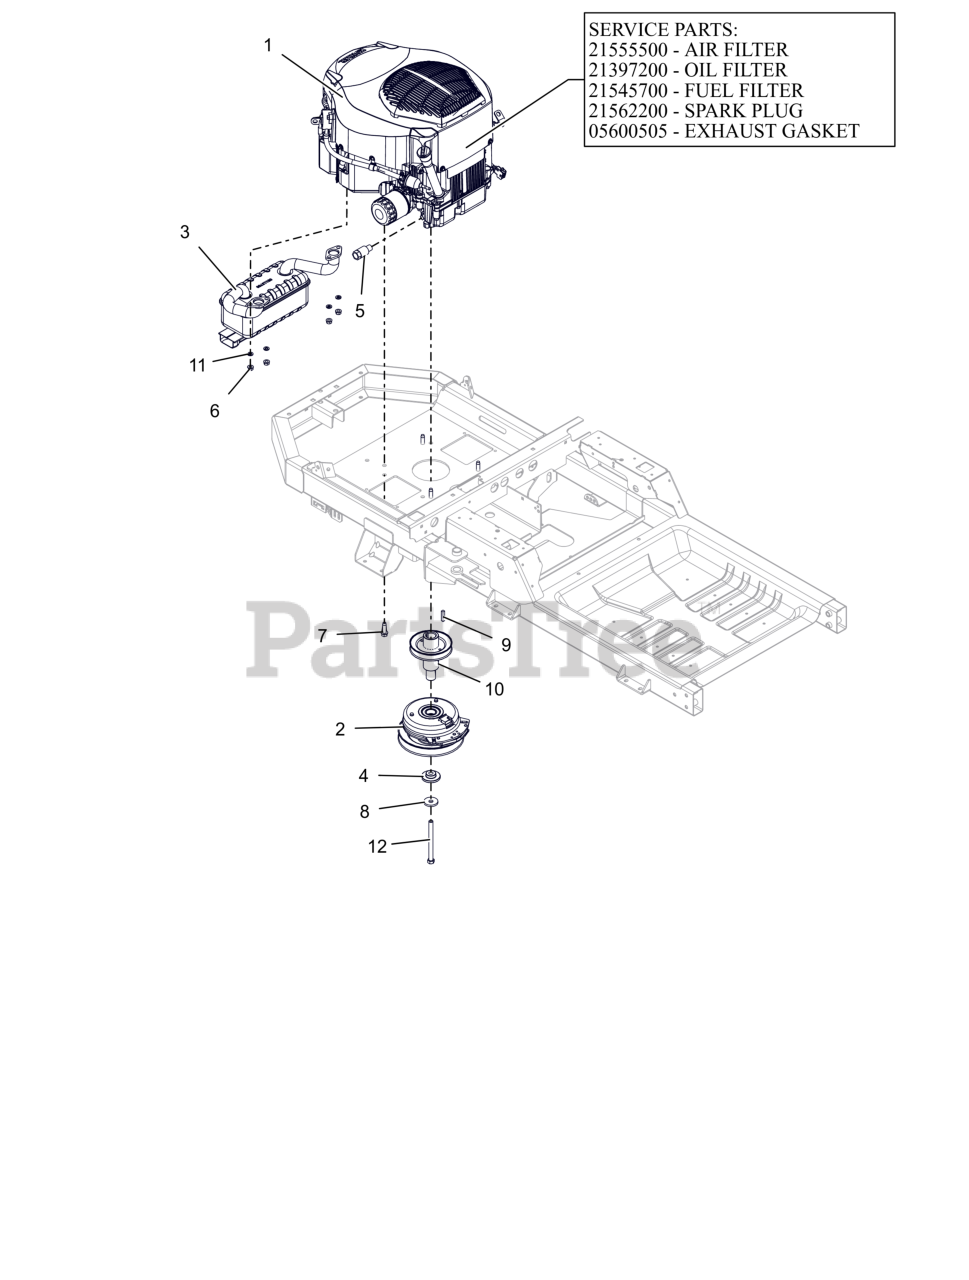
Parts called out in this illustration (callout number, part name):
1	ENGINE, KOHLER 24HP TWIN
1	AIR CLEANER, KOHLER
1	FILTER, OIL - KOH CV20
1	FILTER-FUEL KOHLER COURAGE PRO
1	PLUG, SPARK (RFI)
1	GASKET, MUFFLER KOHLER TWIN
2	CLUTCH,105FTLB MONOPOLE 6.83"
3	MUFFLER, KOHLER
4	BSHG-FLG .469X1.06X.574X2.0
5	DRAIN, OIL
6	NUT-LK-TOP-FLG .312-18 GF ZCC
7	SCR,TAP .375-16X1.25HWH TR ZCC
8	WASHER, 7/16" SPRING DISK
9	KEY-SQ .25 X 1.25 X .25 SAE
10	WLDMT, DRIVE SHEAVE (LONG)
11	WSHR,LK-REG .312X.078 ZCC
12	BLT, HEX .44-20X5.00 G8 ZCC NT
